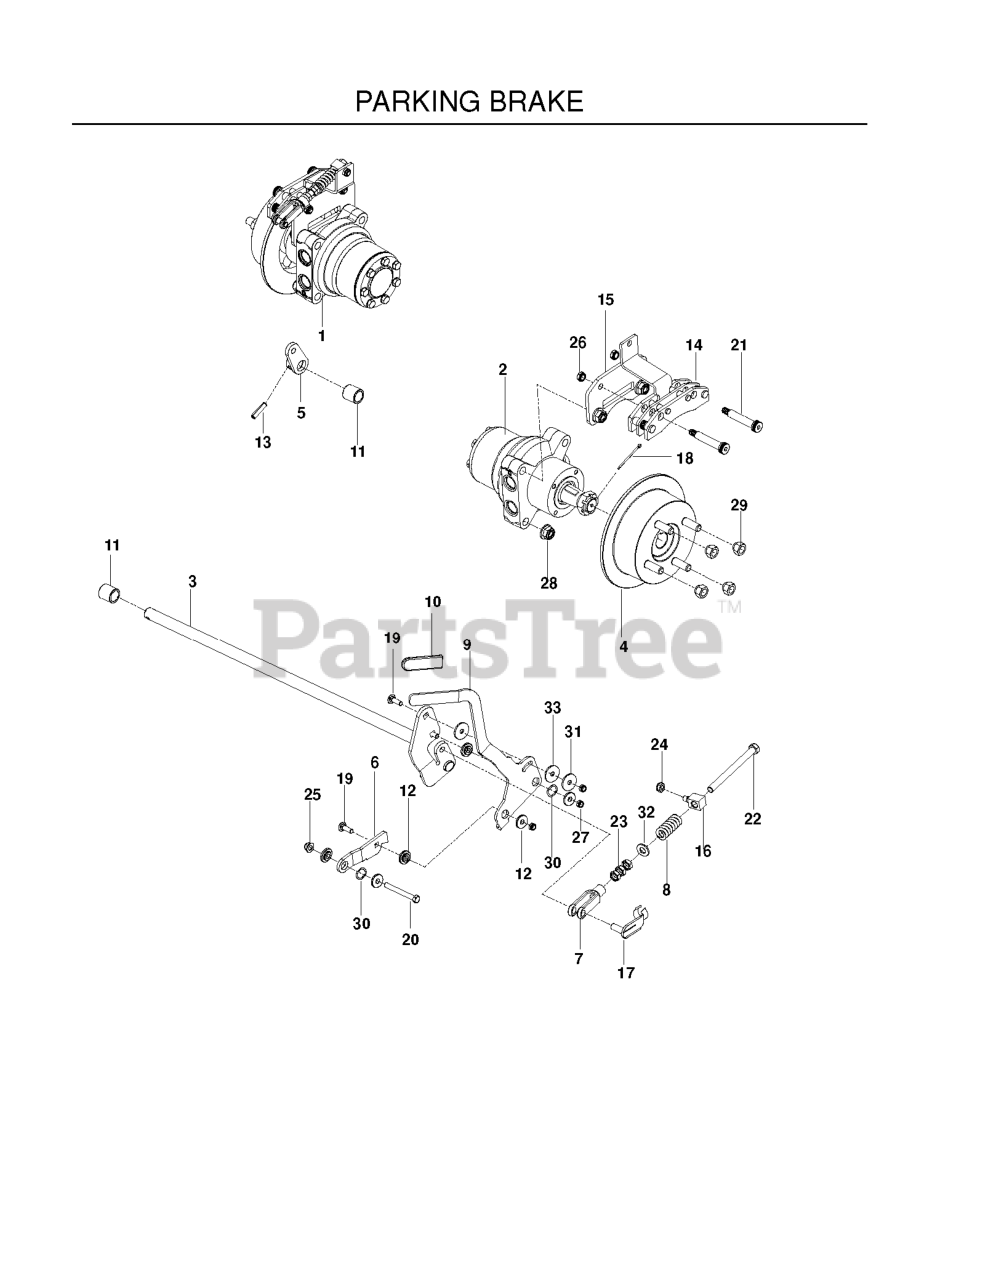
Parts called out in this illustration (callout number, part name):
1	MOTOR, TL0310, RT
2	MOTOR, TL0310, LT
3	SHAFT, BRAKE WLDMT
4	HUB, DISC BRAKE, W/STUDS
5	ARM, RT BRAKE
6	LINK, FOLLOWER
7	YOKE-3/8-24 PLTD
9	LEVER.BRAKE.BLACK
11	BUSHING, SLEEVE 3/4 X 1.0
12	BUSHING, BRAKE
13	5/16 DIA ROLL PIN
15	PLATE, CALIPER
16	SWIVEL, BRAKE
17	PIN, CLEVIS SPRING, 3/8
18	COTTER PIN 1/8 X 2
19	RHSNB 3/8-16 X 1-1/4
20	HCS 3/8-16 X 3-1/4 GR5 ZD
21	BOLT, SHOULDER, 1/2 X 2.25
22	HCS 3/8F X SPECIAL
23	NUT 3/8-24 JAM
24	5/16-18 THIN PROF NY
25	NUT 3/8-16 HEX FLG NYLOC ZD
26	NUT HEX 3/8-16 NYLON, THIN
27	NUT HEX 3/8-16 NYLON, THIN
28	NUT, 1/2-13 HEX FLG NYLOC ZD
29	LUG NUT 1/2F
30	WASHER, .825 X 1.087, WAVE
31	CONE WASHER
32	WASHER 3/8 SAE FLAT
33	WASHER, FRICTION, 1/8
